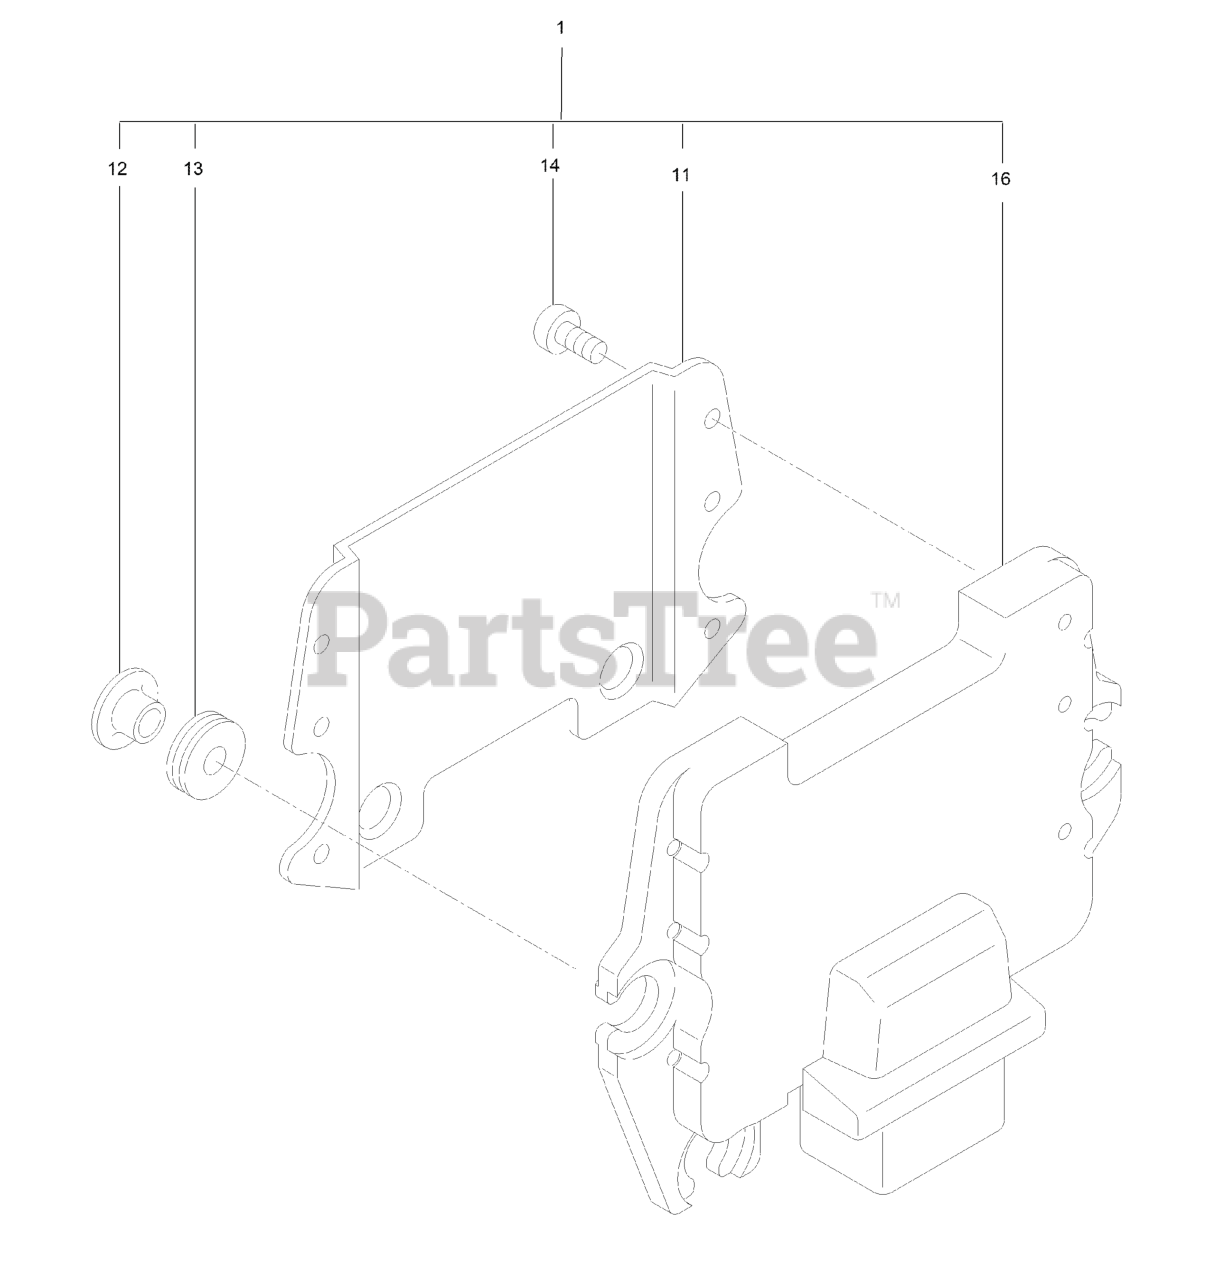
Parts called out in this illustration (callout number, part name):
1	Ecu ASM
13	ABSORBER
16	ECU ASM-SERVICE
